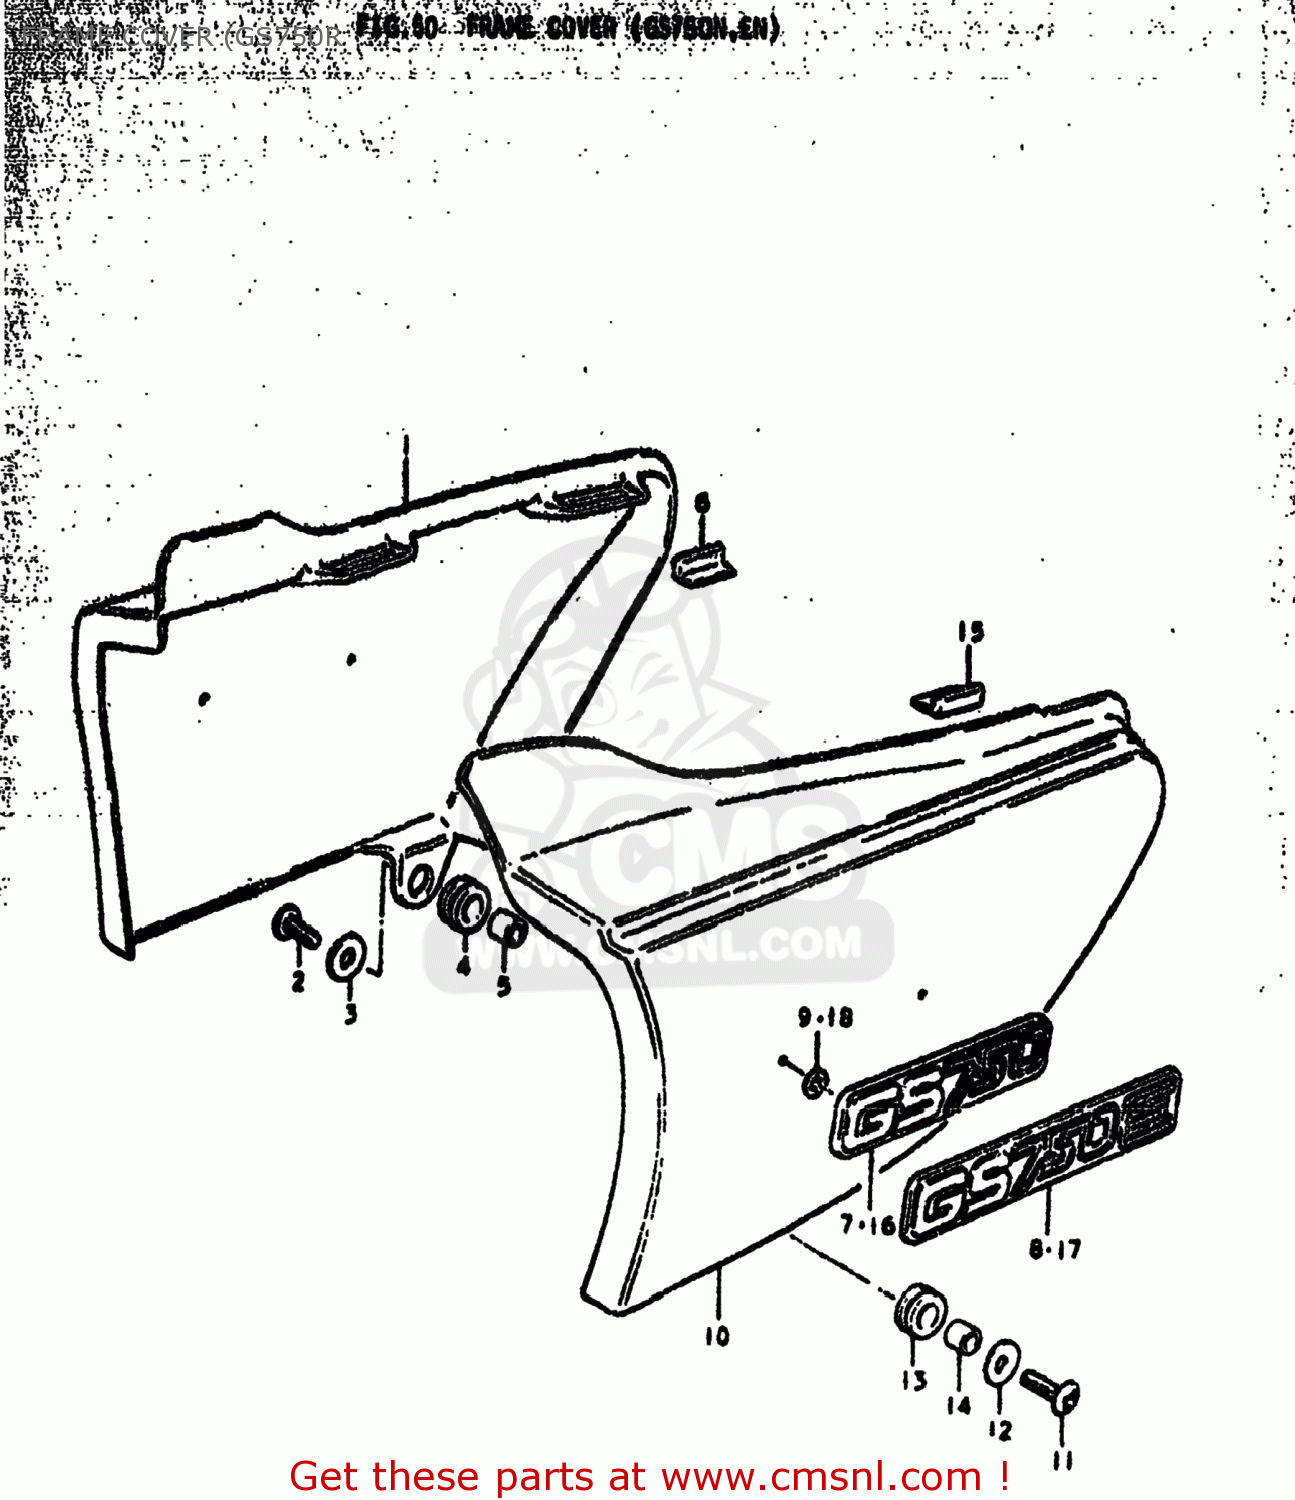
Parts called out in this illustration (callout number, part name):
1	COVER,FRAME,RIGHT
2	SCREW (6X20)
3	WASHER (6.5X20X1.2)
4	CUSHION
5	SPACER (6.8X10X10)
6	CUSHION,FRAME COVER
7	EMBLEM,FRAME COVER
8	EMBLEM,FRAME COVER
9	NUT
10	COVER,FRAME,LEFT
11	SCREW (6X20)
12	WASHER (6.5X20X1.2)
13	CUSHION
14	SPACER (6.8X10X10)
15	CUSHION,FRAME COVER
16	EMBLEM,FRAME COVER
17	EMBLEM,FRAME COVER
18	NUT
